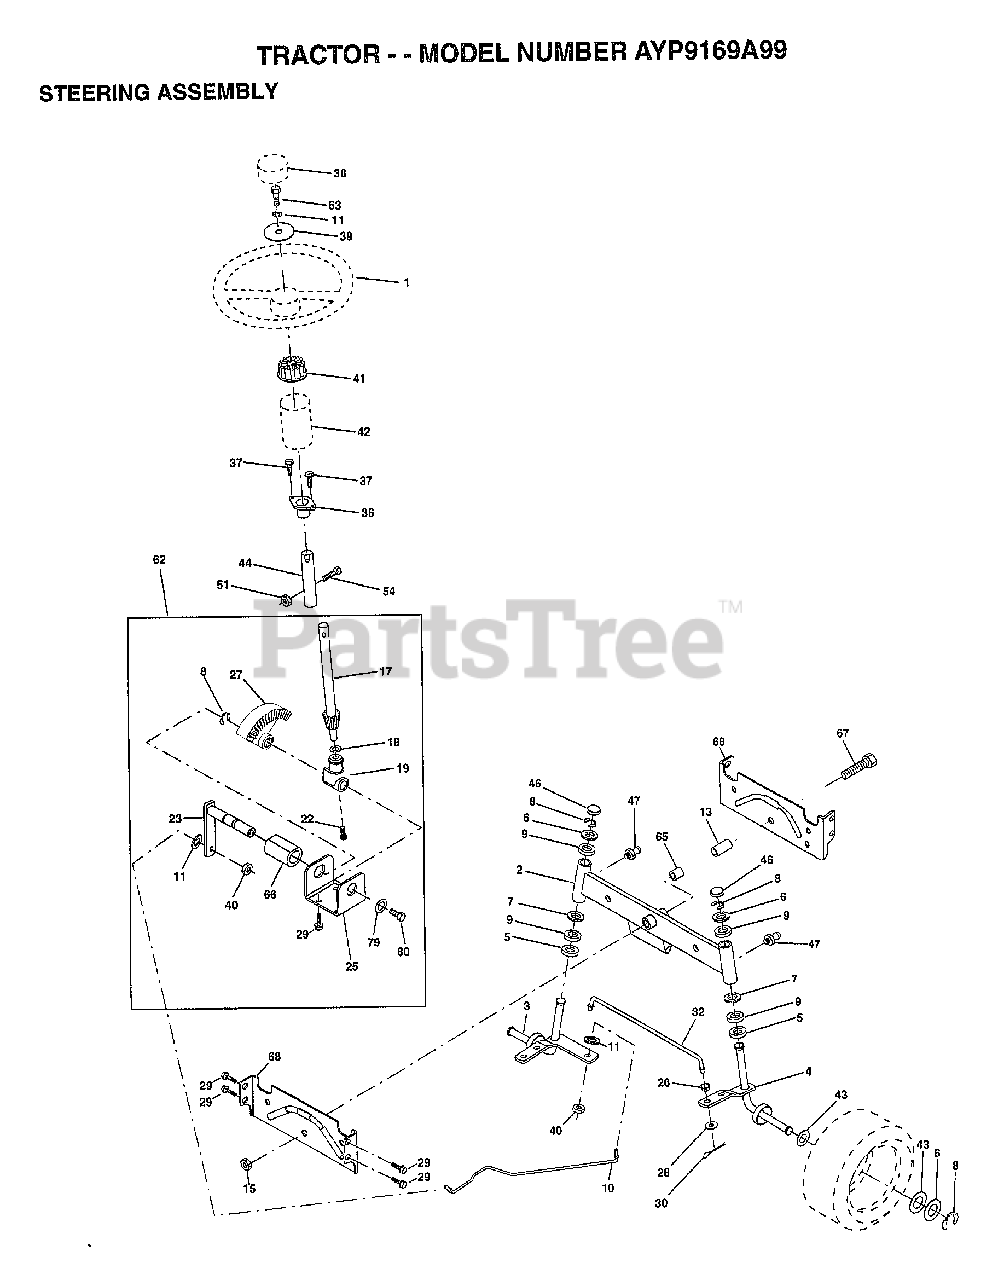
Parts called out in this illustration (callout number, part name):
1	WHEEL STR AYP BLK
2	AXLE ASM
3	SPINDLE.ASM.LH
4	"SPINDLE ASM,RH"
5	WASHER .T
6	WASHER
7	WASHER
8	RING
9	COL. SRTG. BEAR.
10	DRAGLINK-STAMPED
11	LOCKWASHER
13	BEARING AXLE
15	"NUT-LOC,FLANGE LT"
17	SHAFT ASM STEERIN
18	THRUST WASHER
19	SUPPORT.SHAFT.STEER
22	SCREW.HX.WSH.HD
23	SHAFT.ASM.PITMAN
25	BRKT-STEERING
26	BUSHING.DRAGLINK
27	GEAR SECTOR
28	WASHER
29	SCREW
30	COTTER PIN
32	TIE ROD
36	BUSHING.STEERING
37	"SCREW-TT,10-32 FL"
38	CAP STEER AYP
39	WASHER T
40	GRIPCO NUT
41	ADAPTER LT
42	BOOT.STEER.PL
43	WASHER
44	EXT SHAFT STEERIN
46	CAP
47	ZERK M
51	NUT
54	BOLT
62	KIT.STEER.ASM
63	BOLT
65	SPACER AXLE
66	"BEARING-ARM,PITMA"
67	BOLT
68	BRACE AXLE
79	WASHER
80	BOLT.HX.NYLON3/8-16X3/
